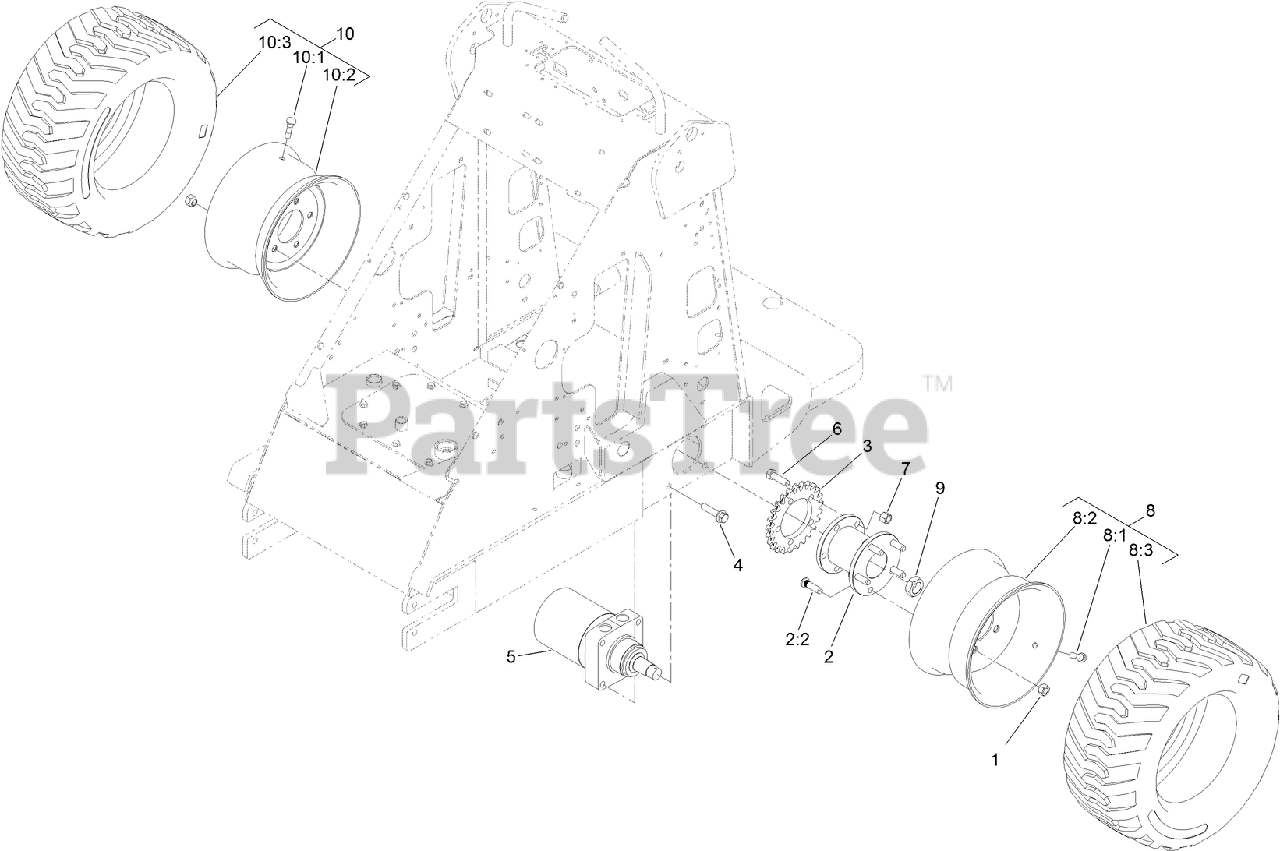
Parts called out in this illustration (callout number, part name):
1	NUT-LUG
2	REAR HUB ASM
2:2	STUD-TYPE, DRIVE
3	SPROCKET-25T
4	SCREW-HHF
5	HYD MOTOR ASM
6	SCREW-HH
7	NUT-LOCK, NI
8	LH WHEEL AND TIRE ASM
8:1	STEM-VALVE
8:2	WHEEL
9	NUT-LOCK
10	RH WHEEL AND TIRE ASM
10:1	STEM-VALVE
10:2	WHEEL
